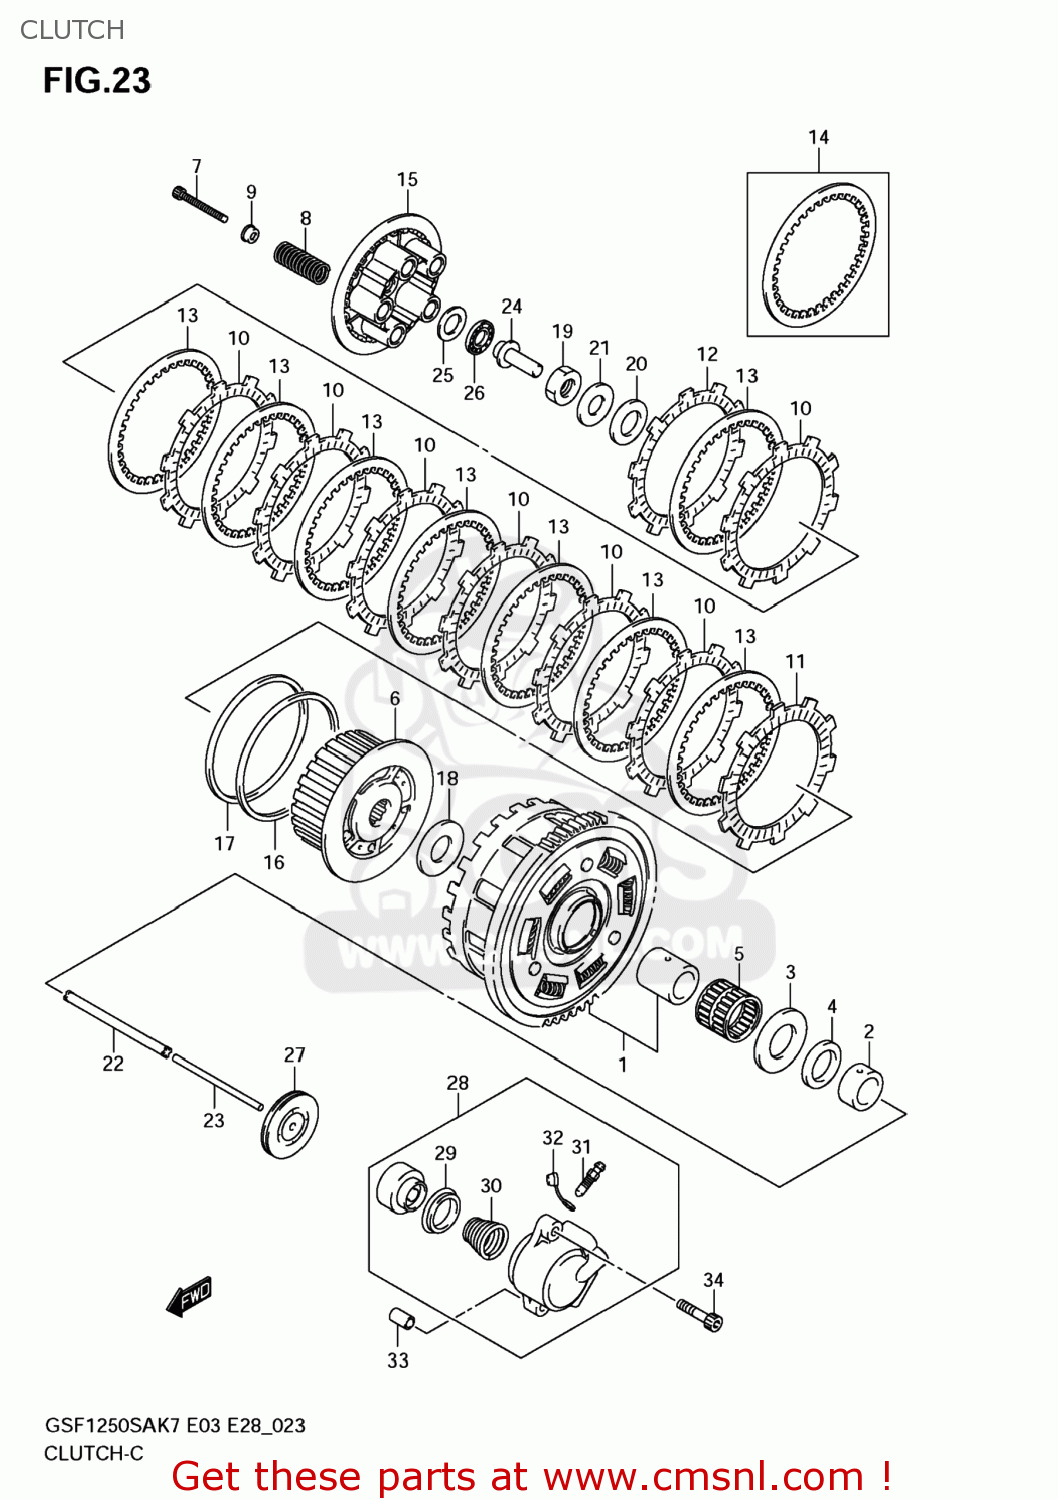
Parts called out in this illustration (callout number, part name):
1	GEAR ASSY,PRIM
2	SPACER,OIL PUMP DRIVE SPROCKET
3	WASHER(25X54X2.4)
4	WASHER(25X30X3)
5	BEARING(35X40X26.8)
6	HUB,CLUTCH SLEEVE
7	BOLT,CLUTCH SPRING
8	SPRING,CLUTCH
9	WASHER
10	PLATE,CLUTCH DRIVE NO.1 (NAS)
11	PLATE,CLUTCH DRIVE NO.3 (NAS)
12	PLATE,CLUTCH DRIVE NO.2 (NAS)
13	PLATE,CLUTCH DRIVEN NO.1(T:2.0 (NAS)
14	PLATE,CLUTCH DRIVEN NO.2(T:2.3 (NAS)
15	DISC,CLUTCH PRESSURE
16	SEAT,WAVE WASHER
17	WASHER,CLUTCH PLATE WAVE
18	WASHER(25X50X2.5)
19	NUT
20	SHIM(25X38X1)
21	WASHER
22	ROD,CLUTCH PUSH,R(L:169)
23	ROD,CLUTCH PUSH,L(L:138)
24	PIECE,CLUTCH PUSH
25	WASHER(15.5X28X1)
26	BEARING(15X28X2)
27	SEAL,OIL(6X52X10)
28	CYLINDER,CLUTCH RELEASE
29	CUP,CLUTCH CYLINDER
30	SPRING,CLUTCH CYLINDER
31	BLEEDER
32	CAP,BLEEDER
33	PIN
34	BOLT(6X30)
